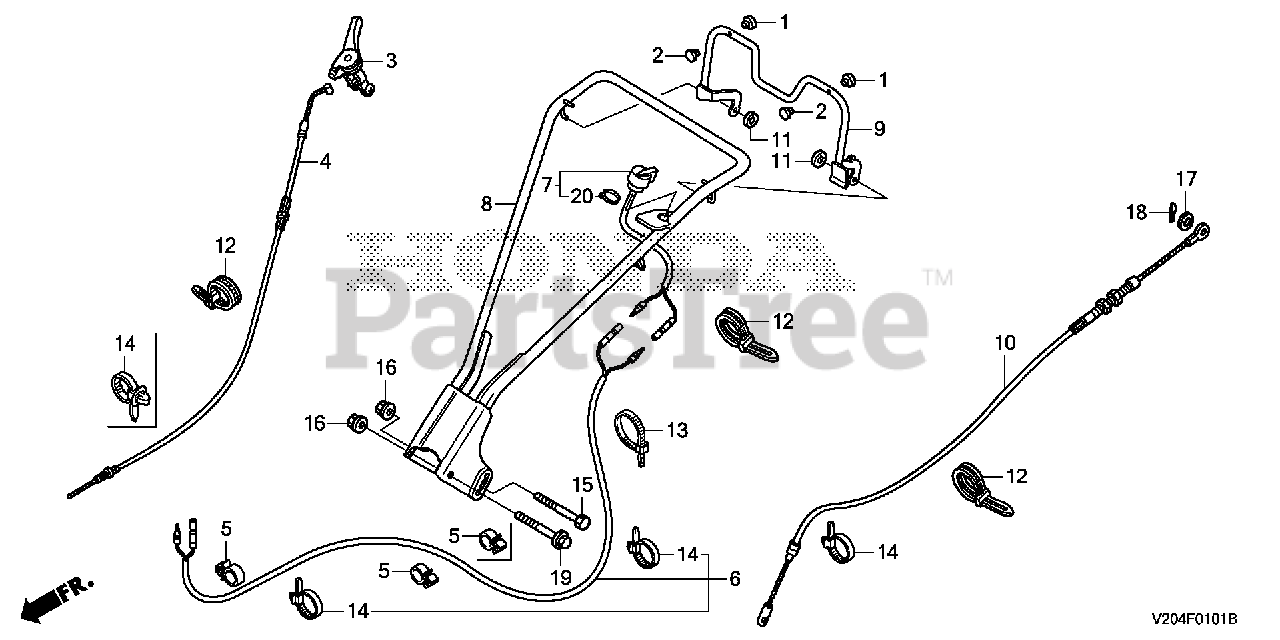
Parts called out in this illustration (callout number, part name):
3	LEVER ASSY., THROTTLE (COO)
4	CABLE, THROTTLE
5	CLIP, HARNESS
6	WIRE, ENGINE STOP SWITCH
7	SWITCH ASSY., ENGINE STOP
8	PIPE, HANDLE *NH105* (MAT BLACK)
9	LEVER, CLUTCH *NH105* (MAT BLACK)
10	CABLE, CLUTCH
11	WASHER, SPECIAL (8MM)
12	BAND, WIRE HARNESS
13	BAND, HARNESS (BLACK)
14	CLIP, HARNESS BAND (145MM) (BLACK)
15	BOLT, HEX. (10X150)
16	NUT, FLANGE (10MM)
17	WASHER, PLAIN (6MM)
18	PIN, SPLIT (2.0)
19	BOLT, FLANGE (10X150)
20	BAND
